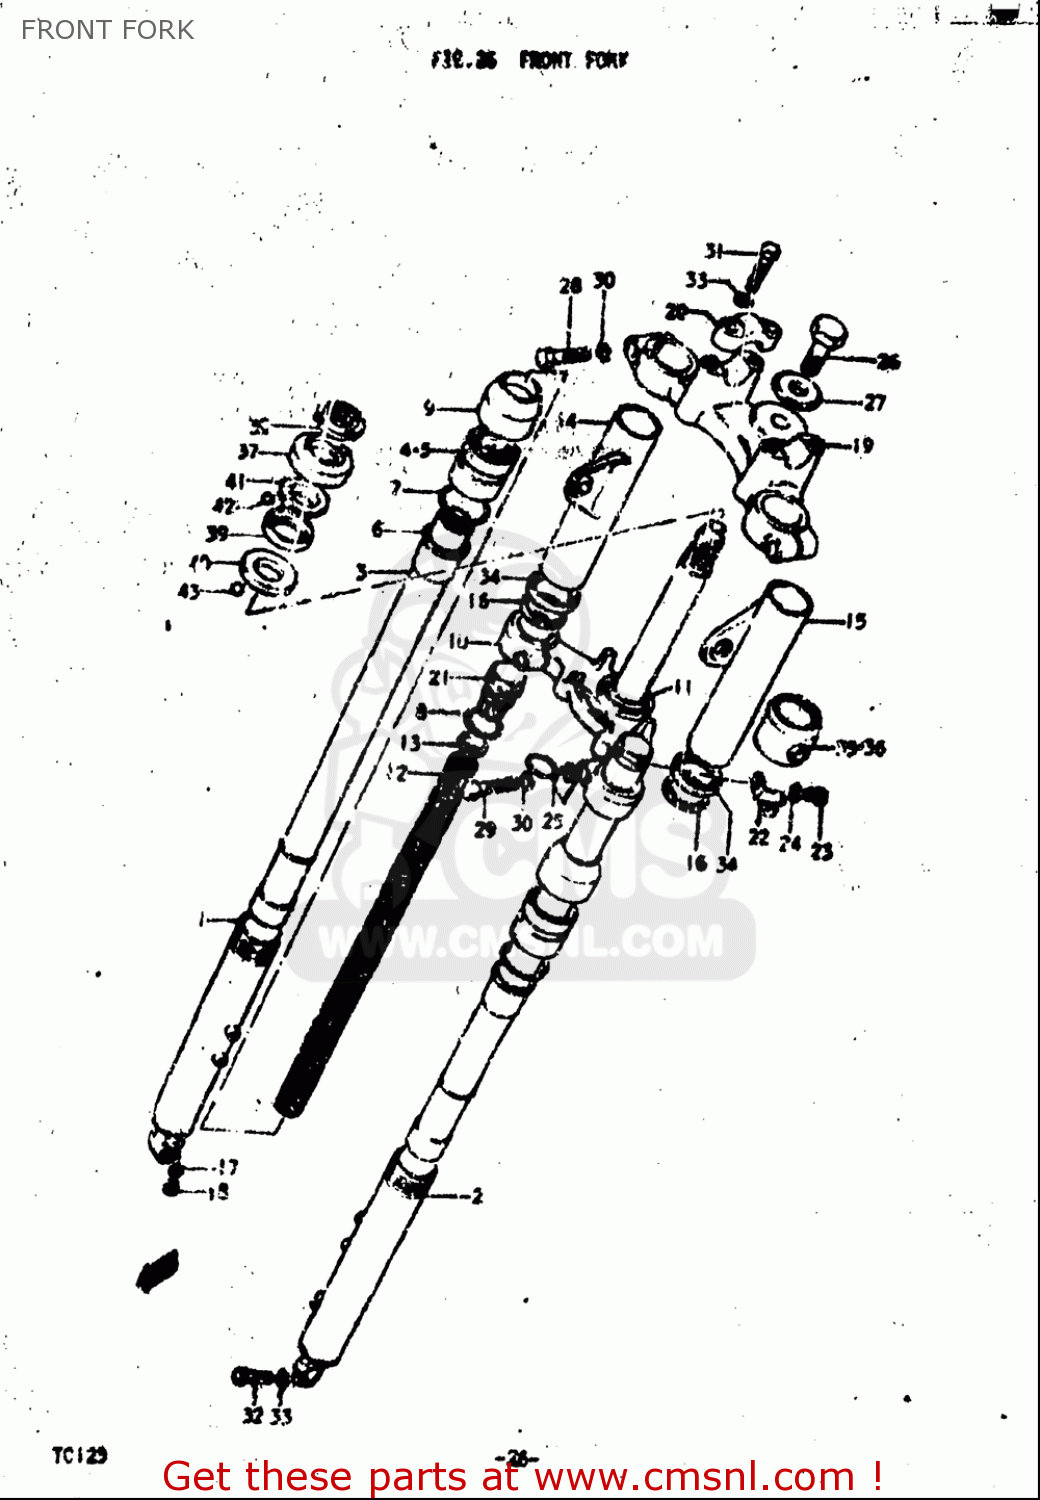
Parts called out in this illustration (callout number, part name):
5	SEAL,OIL
7	O RING,OIL SEAL LWR
8	O RING
9	SEAL,DUST
11	RACE,STEERING OUTER LWR
13	GUIDE,SPRING
17	GASKET,DRAIN,PLUG (NAS)
18	SCREW
20	HOLDER,HANDLEBAR
21	BOLT,FR FORK
22	CLIP
23	SCREW
24	WASHER,LOCK
26	BOLT,FR FORK(10X33)
27	WASHER
30	WASHER,LOCK
31	BOLT
32	BOLT
33	WASHER,LOCK
34	GUIDE, COVER
35	CUSHION,HEADLAMP BRACKET
37	STEERING DUST S
38	NUT,STEERING STEM(25X44X10)
39	RACE,STEERING INNER UPR
40	LACE,STEERING INNER LWR
41	RACE,STEERING OUTER UPR
42	BALL
43	BALL
